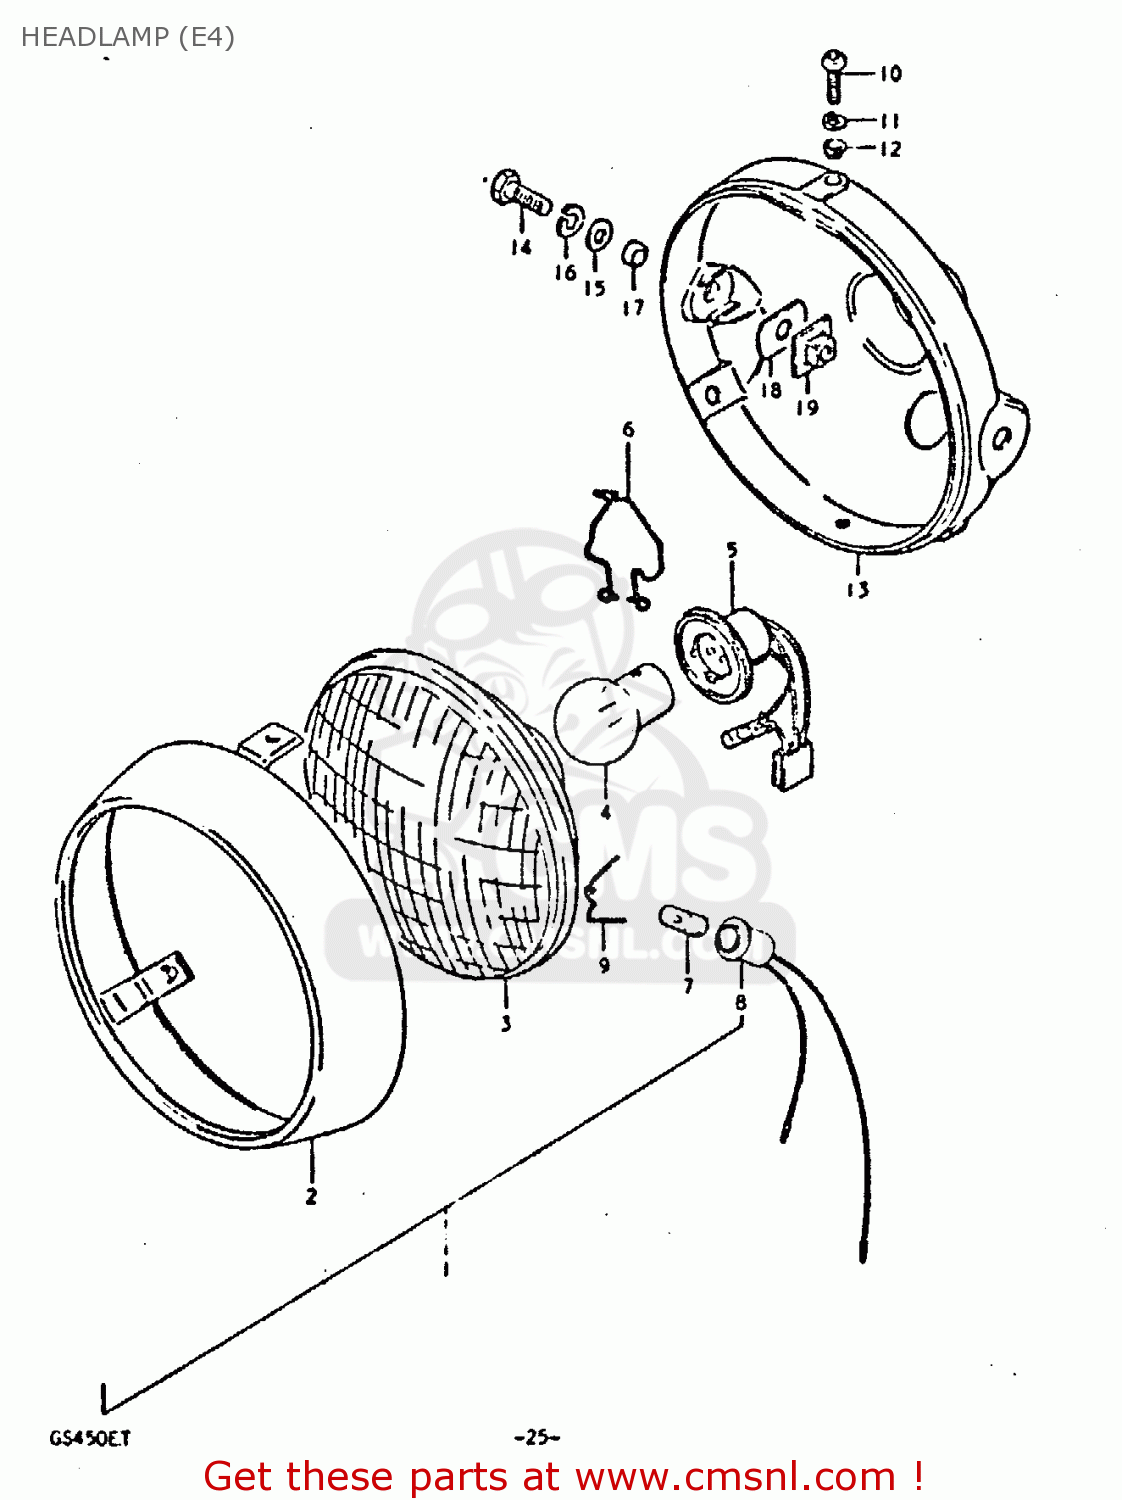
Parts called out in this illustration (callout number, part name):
1	HEADLAMP ASSY
2	RIM
3	UNIT
4	BULB
5	SOCKET
6	CLAMP,HEADLAMP
7	BULB
8	SOCKET
9	SPRING,HEAD LA
10	SCREW
11	WASHER,LOCK
12	WASHER
13	HOUSING,HEADLAMP(BLACK)
14	BOLT
15	WASHER
16	LOCK WASHER
17	SPACER (8.8X12X7)
18	CUSHION
19	PLATE,HEADLAMP HOUSING
